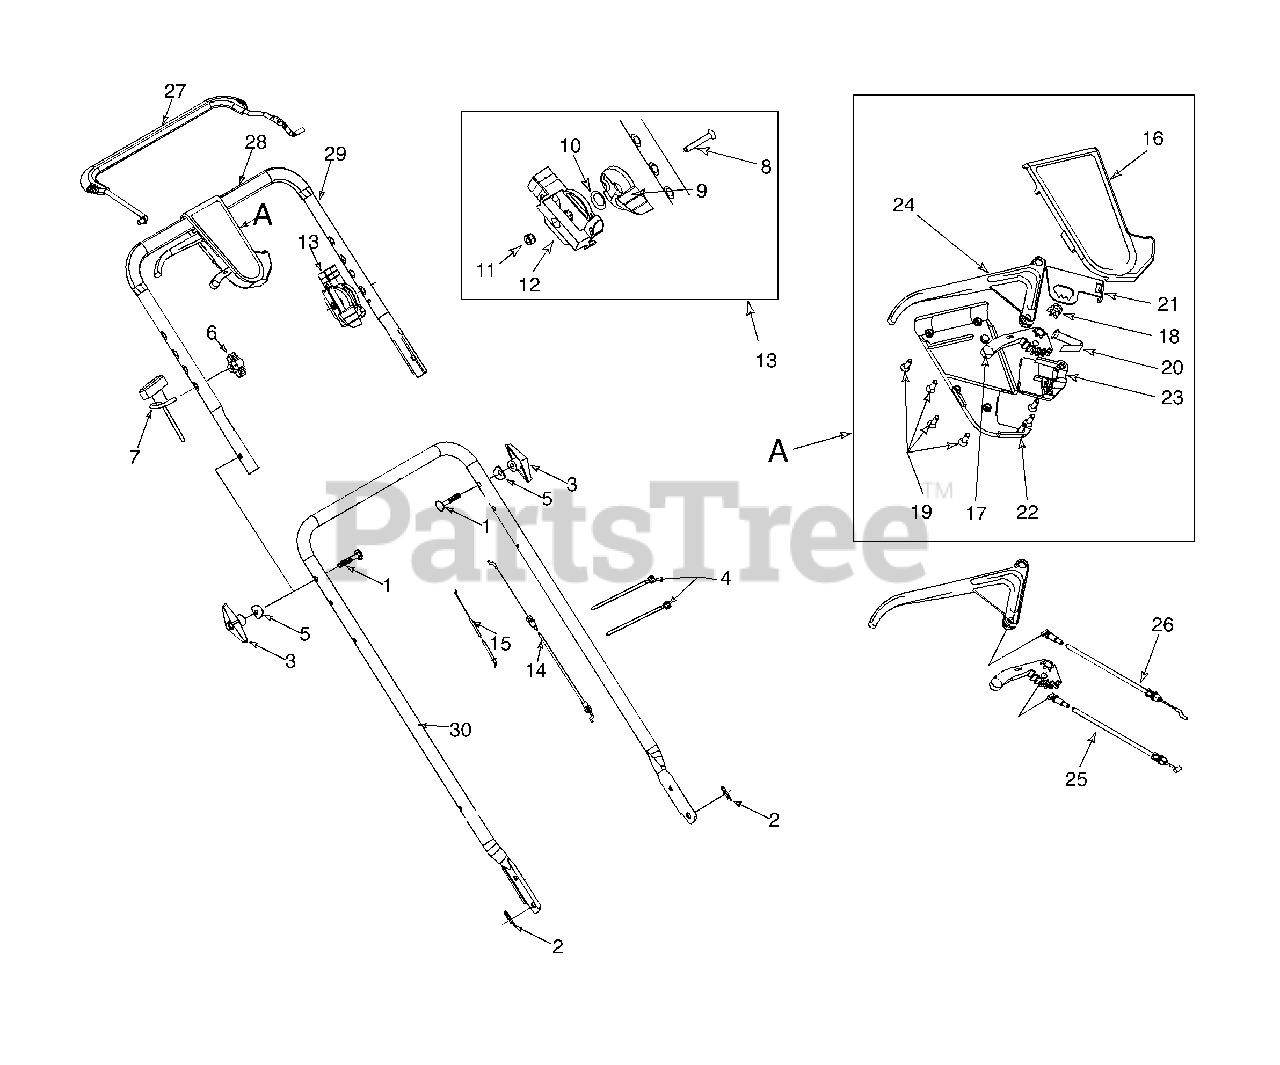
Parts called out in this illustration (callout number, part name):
1	Bolt Curv. Carr. 5/16-18 x 2.0
2	Cotter Pin .072 x 1.12 Lg.
3	Knob Assembly
4	Strap
5	Wash. Sad. .320 ID x.830 OD
6	Knob Handle ERS - 1/4-20
7	Rope Guide Eyebolt
8	Screw 1/4-20 x 1.81
9	Throttle Lever
10	Spring Wash. Curved
11	Nut 1/4-20 Top lock Nut Insert
12	Housing, Throttle
13	Throttle Control -
14	Control Cable 47" Lg.
15	Cable, Throttle 60" Lg.
16	Upper Control Housing
17	6 Speed Shift Lever
18	Gear Insert
19	C. Sunk Tap Scr #10 x .75 L
20	Shift Lever Spring
21	6 Spd. Rack Cable Brkt.
22	Lower Control Housing
23	Cable Mounting Cap
24	Control Lever
25	6 Spd. Cable
26	S.P. Cable
27	Control Handle
28	Foam Grip (2 Reqd.)
